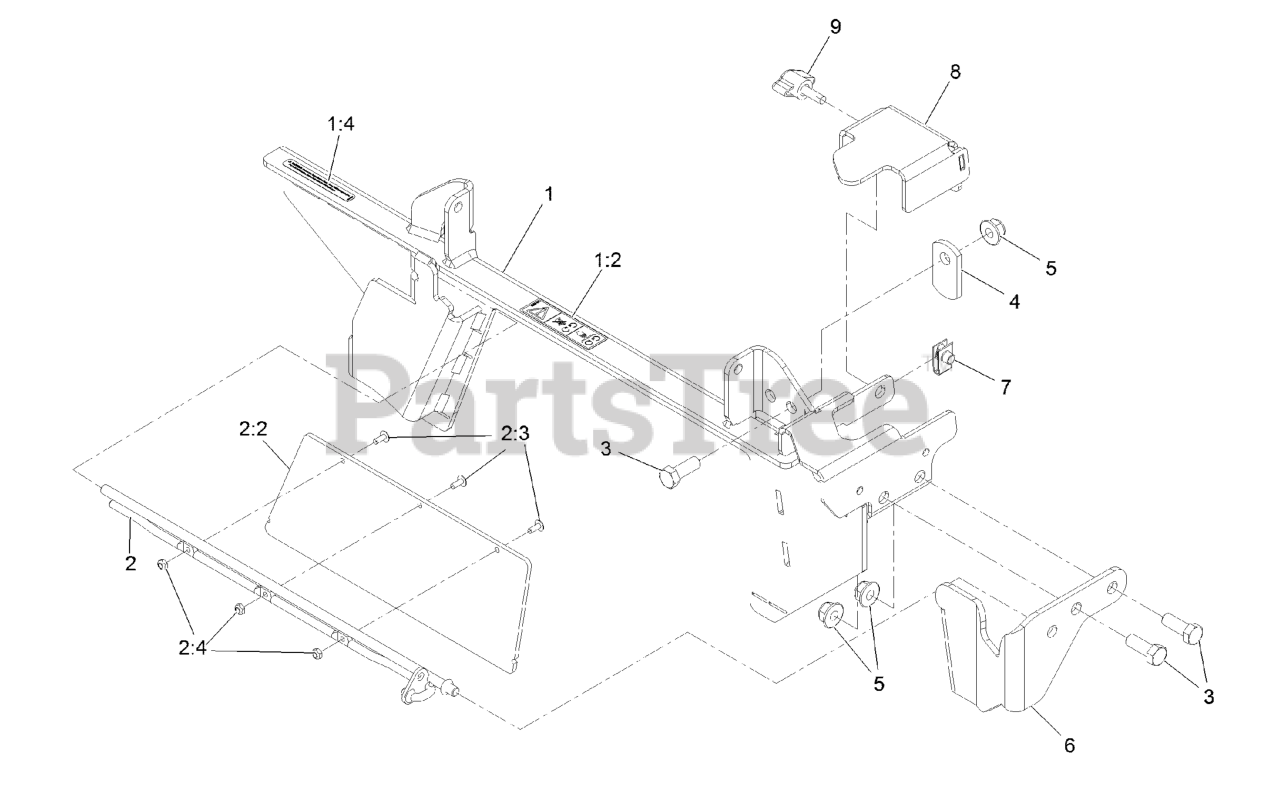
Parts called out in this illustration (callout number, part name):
1	OCD FRAME ASM W/ DECALS
1:2	DECAL, COVER MISSING
1:4	DECAL-WARNING
2	OCD GATE ASM
2:2	GATE-OCD
2:3	SCREW-PTH
2:4	NUT-LOCK, NI
3	SCREW-HH
4	LATCH-CATCHER, GRASS
5	NUT-HF, NI
6	BRKT,CHUTE FRONT
8	BRACKET, CABLE MOUNT
